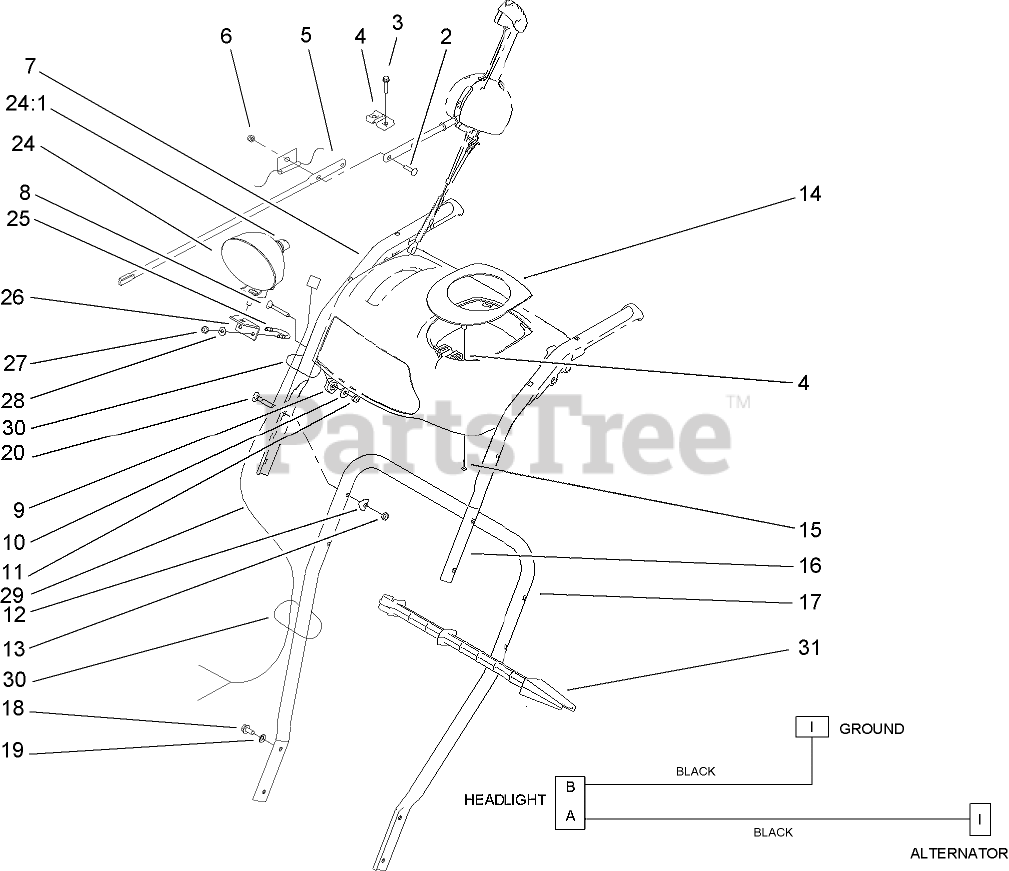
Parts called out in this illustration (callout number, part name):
2	SCREW-CARR
3	SCREW-PLASTITE
4	SUPPORT-ROD
5	ROD-CHUTE, FRONT
6	NUT-LOCK, NI
7	HANDLE-UPPER, RH
8	SCREW
9	CLAMP-CABLE
10	WASHER-PLAIN
11	NUT-LOCK, NI
12	WASHER
13	NUT-LOCK, NI
14	COVER-PANEL, CONTROL
15	SCREW-PPH
16	HANDLE-UPPER, LH
17	HANDLE-LOWER
18	SCREW-HWHTF
19	WASHER-BELLEVILLE
20	SCREW-HANDLE
24	HEADLAMP ASM
24:1	LAMP-12 VOLT
25	CLAMP
26	BRACKET-LIGHT
27	NUT-LOCK, NI
28	WASHER-FLAT
29	HARNESS-WIRE
30	TIE-CABLE
31	STICK-CLEANOUT
